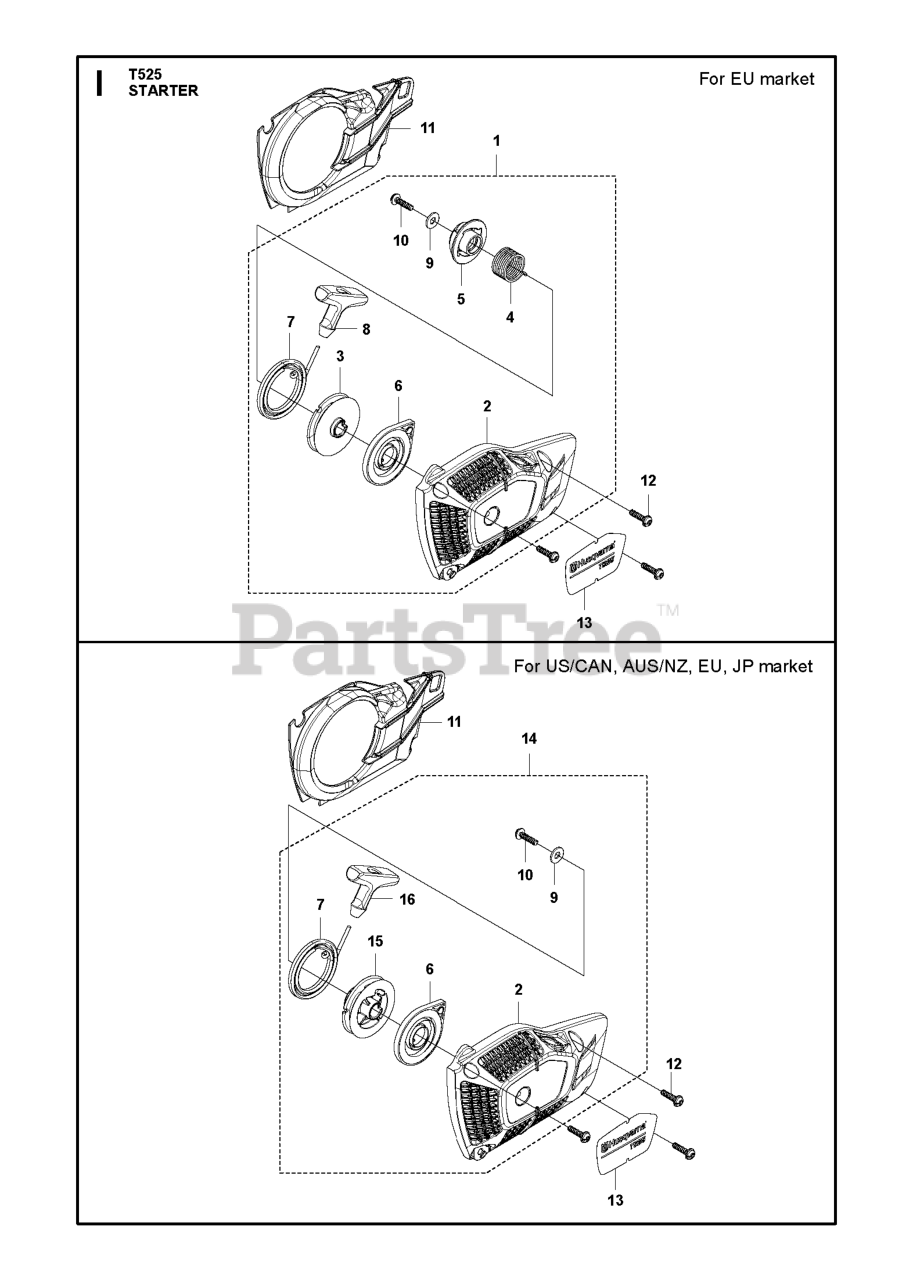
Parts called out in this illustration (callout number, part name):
1	STARTER ASSY
2	STARTER HOUSING ORANGE
3	STARTER PULLEY
8	STARTER HANDLE
10	SCREW (RPLS 267132210)
11	COOLING AIR CONDUCTOR
13	DECAL STARTER
14	STARTER ASSY T525 (WITHOUT DA
15	STARTER PULLEY
16	STARTER HANDLE
